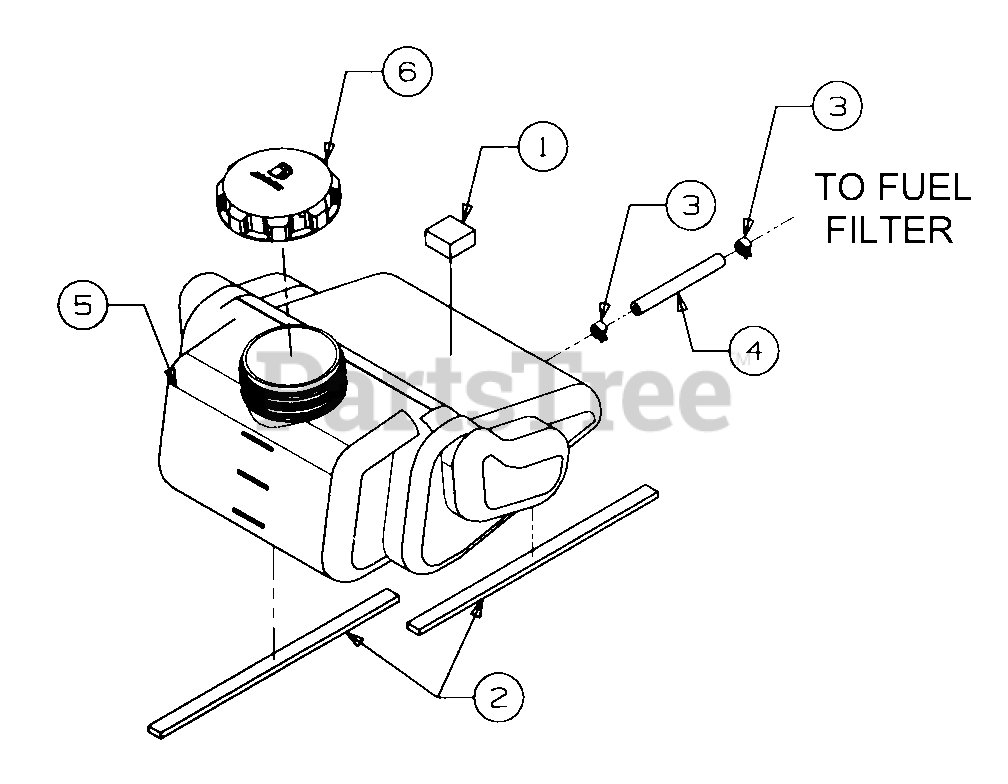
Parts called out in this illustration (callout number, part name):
1	Foam, 1.25 Sq x .62 Thk
2	Tape, Foam, .625 Wide x .25 Thk
3	Clamp, Hose
4	Line, Fuel, 72" (Shipped In 10ft Length)
5	Tank, Fuel
6	Cap, Fuel
